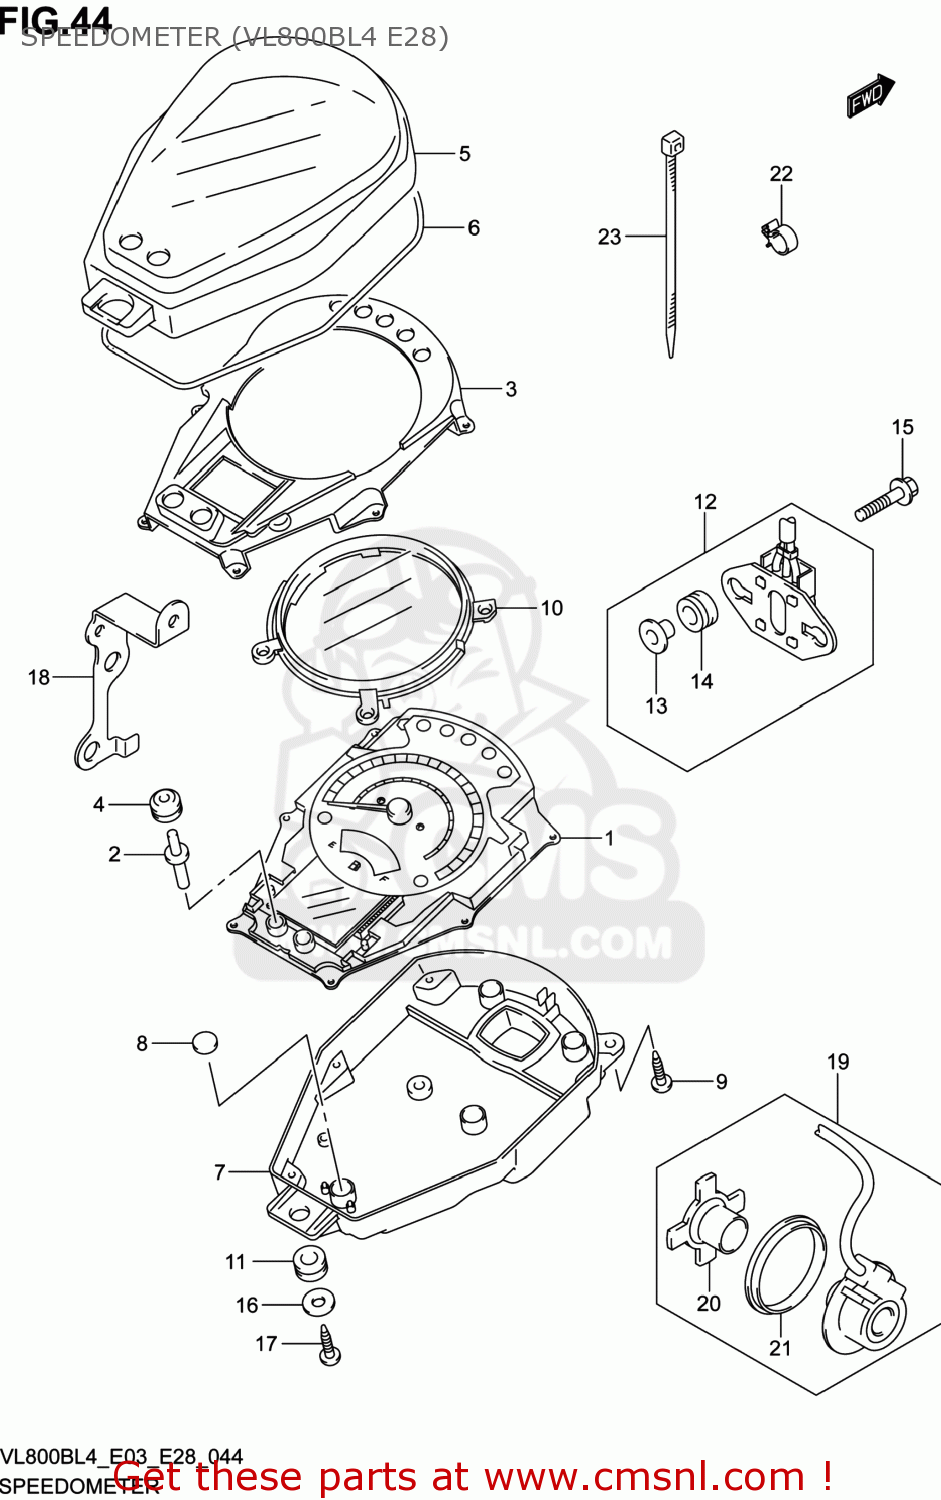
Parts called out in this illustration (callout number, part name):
1	SPEEDOMETER
2	KNOB,SPEEDOMETER
3	PLATE,SPEEDOMETER
4	COVER,SPEEDOMETER
5	CASE,UPR
6	PACKING (NAS)
7	COVER
8	SEAL
9	SCREW(3X12)
10	RING
11	CUSHION,METER
12	RESISTOR ASSY
13	SPACER(6.5X10X11.6)
14	CUSHION
15	BOLT(6X25)
16	WASHER(5.5X16X1.2)
17	SCREW
18	GUIDE,SPEED SENSOR LEAD
19	SENSOR,SPEED
20	MAGNETO
21	SEAL,OIL(44X55X6)
22	CLAMP
23	CLAMP(L:145)
